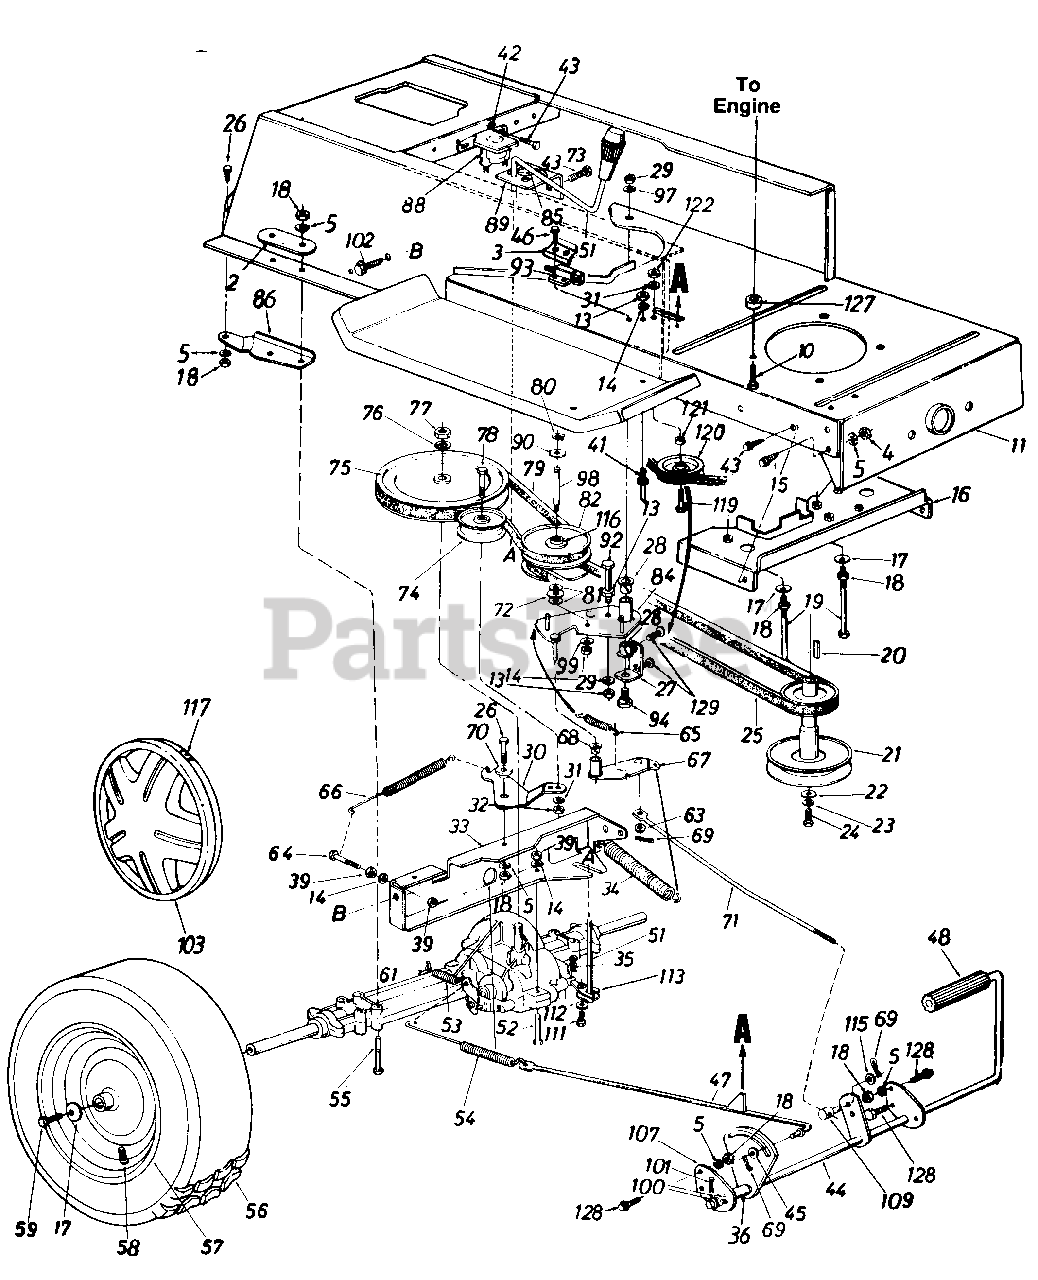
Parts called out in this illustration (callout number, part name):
3	Switch Plate
4	Hex Nut 5/16-24 Thd.
5	L-Wash. 5/16" I.D.
10	Hex Wash Hd. AB-Tap Scr. 3/8-16 Thd.
11	Lower Frame Ass'y.
13	Hex Nut 1/4-20 Thd.
14	L-Wash. 1/4" I.D.
15	Hex TT-Tap Scr. 5/16-18 x .62"
16	Belt Guard Brkt. Ass'y.
17	Bell-Wash. .345" I.D. x .88"
18	Hex Nut 5/16-18 Thd.
19	Hex Bolt 5/16-18 x 4.0"*
20	Sq. Key 1/4" x 1/4" x 2.00"
21	Engine Pulley
22	Fl-Wash. 7/16" I.D. x 1.25"
23	L-Wash. 7/16" I.D.
24	Hex Bolt 7/16-20 x 1.50" Lg.
25	Variable-Speed Belt
26	Hex Bolt 5/16-18 x .75" Lg.
27	Bearing Shaft Bracket Ass'y.
28	Flanged Nyliner Brg. 5/8" I.D. x .88" Lg.
29	Hex Nut 3/8-24 Thd.
31	L-Wash. 3/8" I.D.
32	Hex Nut 3/8-24 Thd.
33	Transaxle Support Brkt.
34	Ext. Spring .94" O.D. x 7.58"
35	Inter. Cotter Pin
36	Spacer.63" I.D.
39	Hex Nut 1/4-28 Thd.
41	Belt Guard Pin
42	Ext. L-Wash. 1/4" I.D.
43	Hex Wash. Hd. S-Tap Scr. 1/4-20 x .50" Lg.
44	Clutch/Brake Pedal Ass'y.
45	Fl-Wash.
46	Truss Mach. Scr. B-Tap Scr. #10 x .5" Lg.
47	Brake Rod Ass'y.
48	Foot Pad
51	Shift Lever Ass'y.
52	Hex Bolt 1/4-28 x 1.75" Lg.
53	Ext. Spring .38" O.D. x 2.5"
54	Ext. Spring .59" O.D. x 7.08"
55	Hex Bolt 5/16-18 x 2.75"
57	Wheel Rim Only
58	Air Valve
59	Hex Bolt 5/16-24 x .75" Lg.
61	Brake Return Spring Anchor
63	Fl-Wash. .34" I.D. x .68" O.D.
64	Hex Bolt 1/4-28 x 1.25" Lg.
65	Ext. Spring
66	Ext. Spring .62" O.D. x 6.12"
68	Flanged Bearing
69	Cotter Pin 3/32" Dia.
70	Shoulder Spacer 27" Lg.
71	Speed Control Link
72	Truss Bearing .56 Dia. x 1.25"
73	Shift Knob
74	Fl-ldler Pulley 3.25" x .75"
75	1/2" "V"-Pulley
76	L-Wash. 1/2" I.D.
77	Hex Jam Nut 1/2-20 Thd.
78	Hex Bolt 3/8-24 x 1.75n Lg.
79	Variable Speed Belt
80	Snap Ring 56" Dia.
82	Variable Speed Pulley Ass'y. 5n O.D.
90	Teflon Washer 565" l.D.
92	Hex Bolt 1/4-20 x 3.25" Lg.
93	Safety Switch
94	Shld. Bolt 3/8-24 x 3.12" Lg.
97	Bell-Wash. 88" l.D. x .88"
98	Shaft S6n Dia. x 3.875" Lg.
99	Bell-Wash. 39" l.D. x 1.12"
100	Fl-Wash. .641" I.D. x 94"
101	Cotter Pin 1/8" Dia. x 1.25
102	Hex Wash. Hd. Scr. 5/16-18 x 62" Lg.
103	Hub Cap
109	Ferrule
111	Hex Bolt 1/4-28 x 50" Lg.
112	Bell-Wash. .265" l.D. x 75"
113	Shift Lever Link Ass'y.
115	Fl-Wash. .385" I.D. x .62"
116	Needle Brgs.
117	Spring Clip
119	Hex Bolt 3/8-16 x 1.25" Lg.
120	Fl-ldler w/Flanges 2 75" O.D.
121	Fl-Wash. 39n l.D. x 1.12" O.D.
122	Hex Nut 3/8-16 Thd.
127	Spacer 5/16n l.D.
128	Hex Wash. TT-Tap Scr. 5/16-18 x.75" Lg.
129	Hex Wash. AB-Tap Scr. 5/16-18 x .75" Lg.
